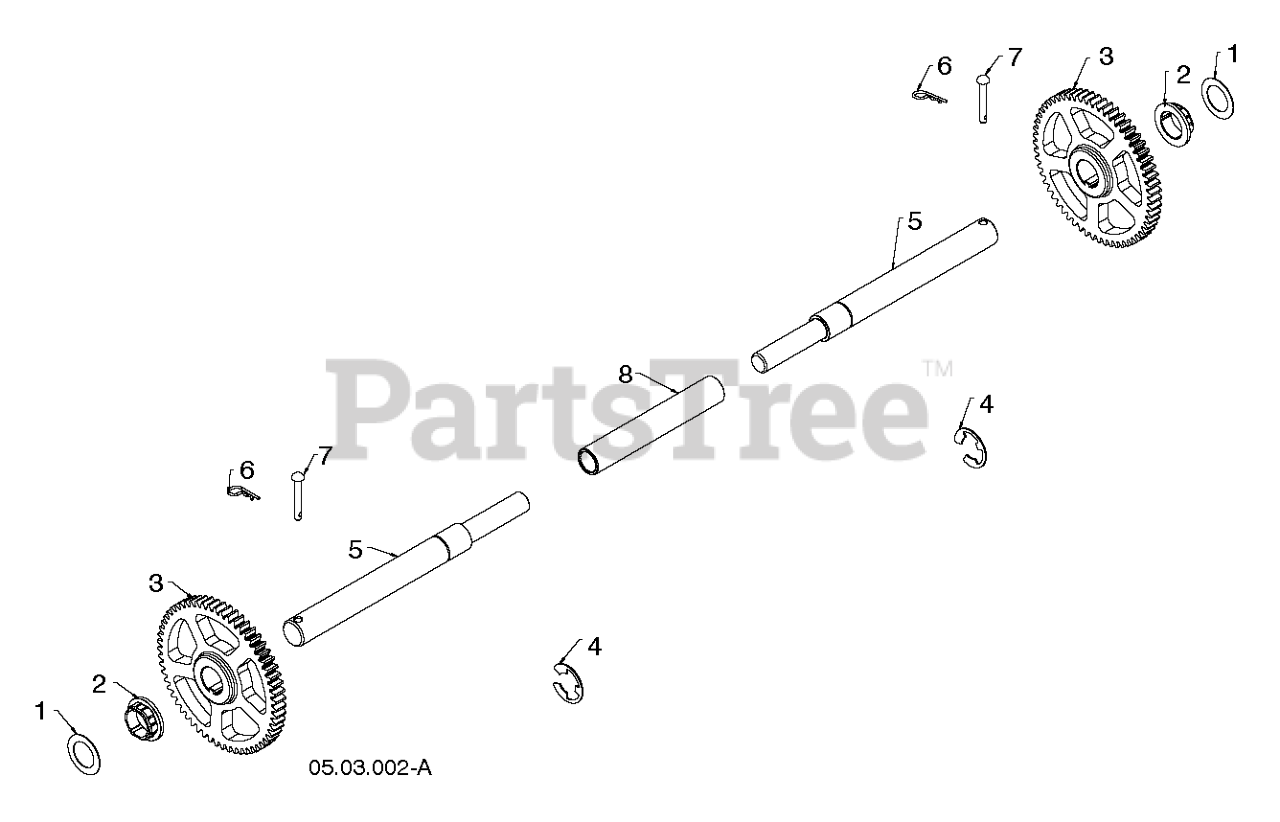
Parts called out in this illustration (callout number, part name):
1	WASHER 1.00
2	BUSHING.HEX.1.SHAFT
3	GEAR.59T
4	E-Ring (AYP part number)
5	AXLE AXLE, SPLIT SHAFT
6	Spring Retainer 1" Zinc/cad (AYP part number)
7	RIVET
8	SLEEVE SLEEVE, AXLE SLEEVE
